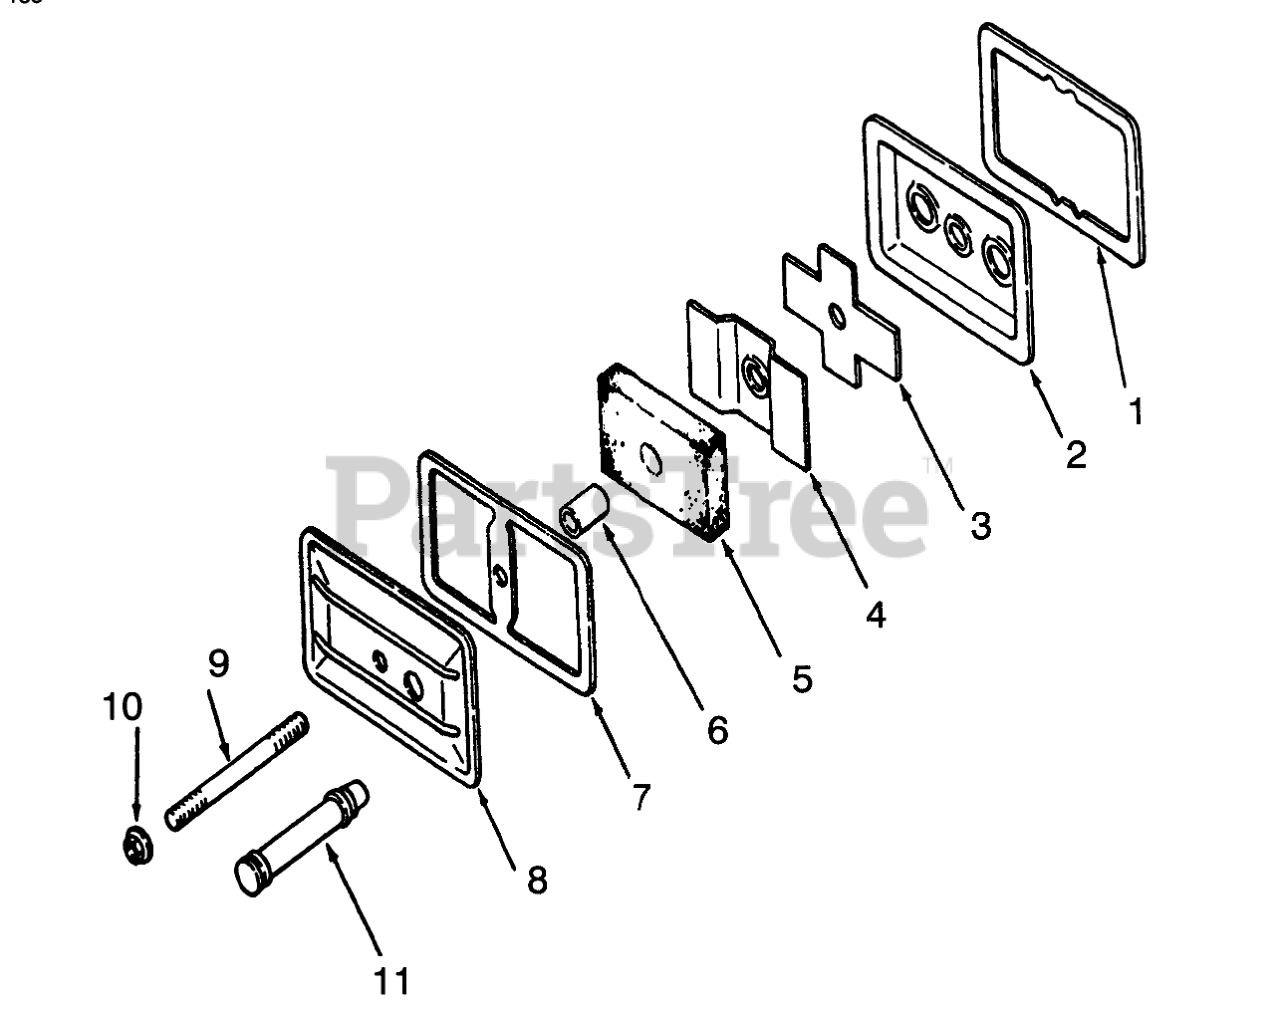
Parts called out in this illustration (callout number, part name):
1	Gasket
2	Plate
4	Baffle
5	Filter
7	Gasket
8	Cover
10	Palnut
